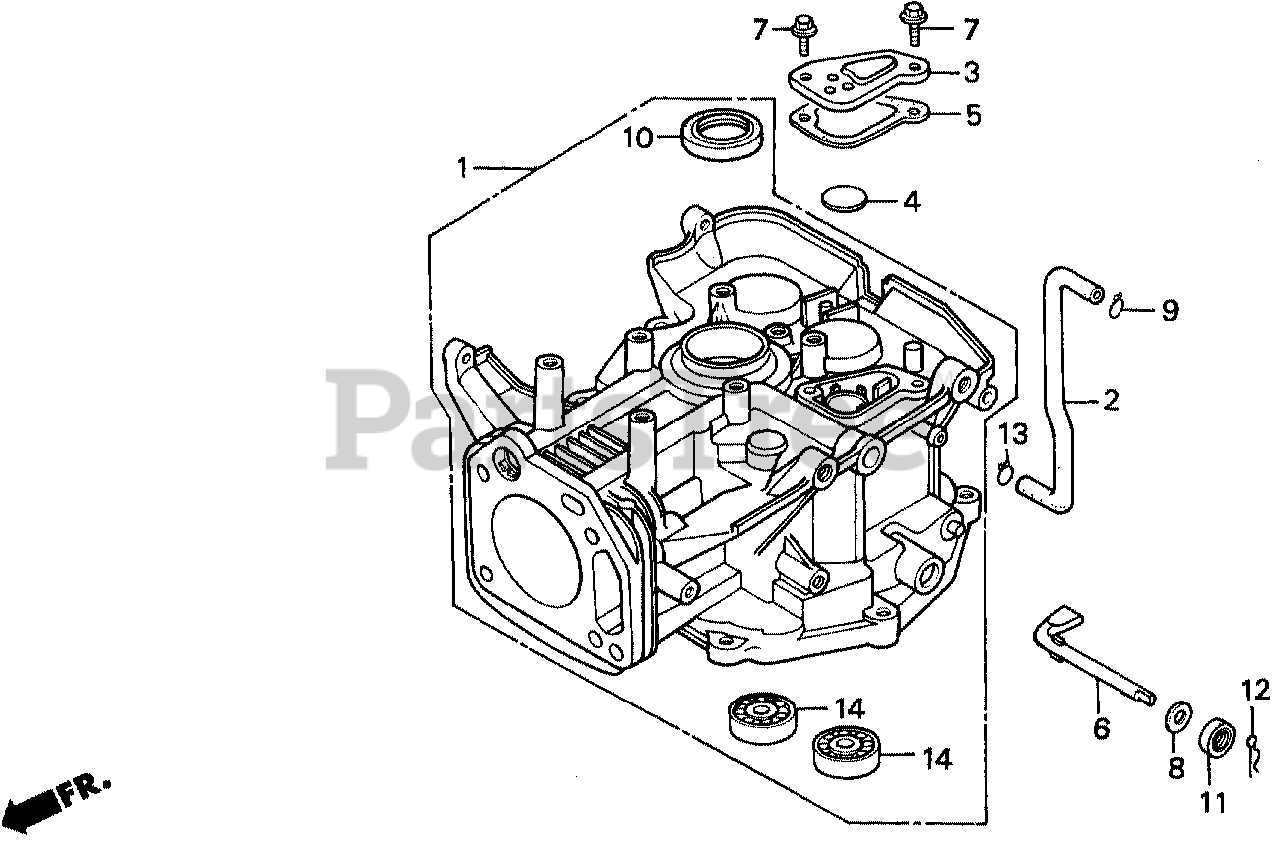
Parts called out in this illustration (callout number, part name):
1	CYLINDER ASSY.
2	TUBE, BREATHER
3	CAP, BREATHER CHAMBER
4	VALVE, BREATHER
5	GASKET, BREATHER CAP
6	SHAFT, GOVERNOR ARM
7	BOLT, FLANGE (6X12) (CT200)
8	WASHER, THRUST (8.1MM)
9	CLIP, TUBE
10	OIL SEAL (35X52X8)
11	OIL SEAL (8X14X5)
12	PIN, LOCK (8MM)
13	CLIP, TUBE (C11)
14	BEARING, RADIAL BALL (6202)
